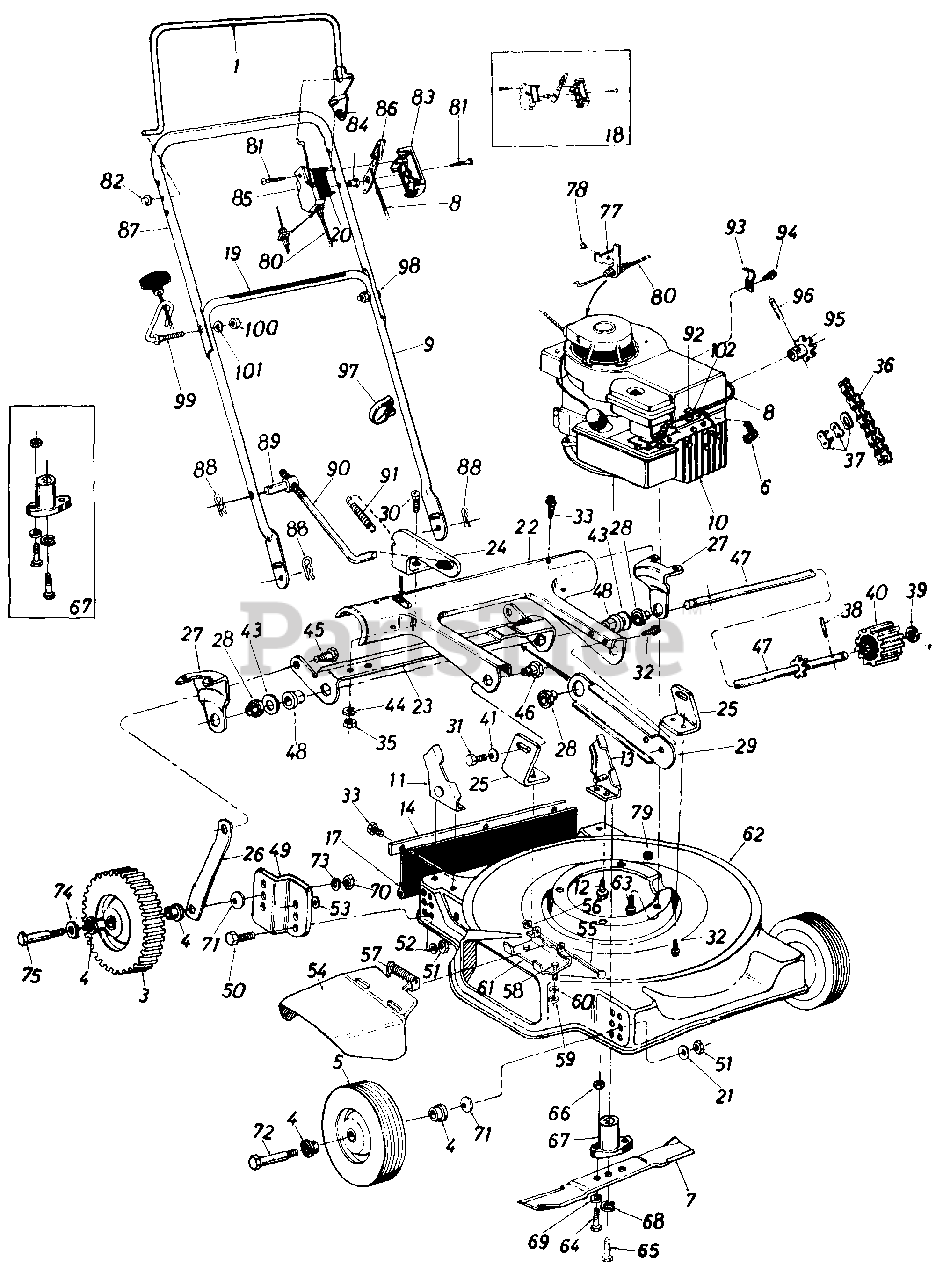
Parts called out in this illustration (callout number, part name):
1	Control Handle Ass'y.- L.H.
3	Wheel Ass'y. Comp. - Rear 8 x 1.75
4	Flange Brg. - Plastic 1/2" I.D.
5	Wheel Ass'y. Comp. - Front 7 x 1.50
6	Spark Plug Boot
7	Blade 22"
8	Throttle Wire - 53.0"
9	Lower Handle
10	Engine
11	Handle Brkt. Ass'y. - R.H.
12	Hex Wash. Hd. "B" - Tap Scr. 5/16-18 x .50" Lg.
13	Handle Brkt. Ass'y. - L.H.
14	Retainer Strip
17	Rear Flap Ass'y.
18	Kit - Control Housing Comp.
19	Instruction Label - Handle
20	Control Label - Throttle
21	Bell - Wash. .39 I.D. x 1.13
22	Pinion Pivot Cover 22"
24	Engagement Arm
25	Pivot Brkt.
26	Link 4.58 x .88
27	Axle Brkt.
28	Flanged Ball Brg. .500" I.D.
29	Brg. Support
30	Carriage Bolt 1/4-20 x .50" Lg.
31	Hex Bolt 3/8-16 x .50" Lg.
32	Hex "B"-Tap Scr. 1/4" x .38" Lg.
33	Hex Wash. Hd. "AB"-Tap Scr. 1/4" x .62" Lg.
35	Hex Nut 1/4-20 Thd.
36	#48 Chain 1/2" Pitch 50 Links - E.
37	#48 Master Link
38	Spring Pin Spir. 3/16" Dia. x 1.25" Lg.
39	"E"-Ring for .500" Dia. Shaft
40	Drive Pinion
41	Bell-Wash. .400" I.D. x .88" O.D. x .060
43	Fl-Wash. .531" I.D. x .930" O.D. x .050
44	L-Wash. 1/4" I.D.
45	Shld. Bolt .437" Dia. x .162
46	Shld. Nut .625" Dia. x .162
47	Pinion Shaft w/7 Tooth Sprocket
48	Hex Flange Brg. x .506" I.D. Plastic
49	Wheel Brkt.
50	Hex Bolt 3/8-16 x .75" Lg.
51	Hex Nut 3/8-16 Thd.
52	Bell-Wash. .400" I.D. x .88"
53	Fl-Wash. .38" I.D. x .620"
54	Chute Deflector Ass'y. Comp
55	Pivot Pin
56	Cap Speed Nut 1/4" Rod
57	Torsion Spring
58	Hex Bolt 1/4-20 x .50" Lg.
59	Hex Nut 1/4-20 Thd.
60	L-Wash. 1/4" I.D.
61	Hinge Plate
62	22" Deck Ass'y.
63	Hex Wash. Hd. TT-Tap Scr. 3/8-16 x 1.0" Lg.
64	Hex Bolt 5/16-24 x 1.00" Lg. (Grade 5) Special
65	Hex Bolt 3/8-24 x 2.25" Lg. (Grade 5)
66	Hex Nut 5/16-24 Thd.
67	Blade Adapter Kit
68	L-Wash. 3/8" I.D. - H.D.
69	L-Wash. 5/16" I.D.
70	Hex Nut 3/8-16 Thd.
71	Bell-Wash. .400" I.D. x .88"
72	Front Axle Bolt
73	L-Wash. 3/8" I.D.
74	Fl-Wash. .531" I.D. x .93"
75	Rear Axle Bolt
77	Cable Bracket
78	Pop Rivet .156" Dia. x .379
80	Control Cable - 39.0"
81	Truss Mach. Self - Tap Scr. #12 x 1.50" Lg.
82	Cap Speed Nut 5/16" Rod
83	Control Panel Half
84	Control Disc Pin
85	Clutch Panel Half
86	Throttle Control Lever
87	Upper Handle
88	Hairpin Cotter
90	Clutch Rod
91	Extension Spring - 3/8" O.D. x 2.10" Lg.
92	Casing Clamp
93	Casing Clamp
94	Hex "B"-Tap Scr. #10 x .38"
95	10 Tooth Sprocket Ass'y.
96	Spiral Pin 3/16" Dia. x 1.00"
97	Cable Tie
98	Curved Hd. Carriage Bolt 5/16-18 x 1.38" Lg.
99	Rope Guide Bolt
100	Hex Nut 5/16-18 Thd.
101	L-Wash. 5/16" I.D.
102	Hex AB-Tap Scr. #8 x .38"
